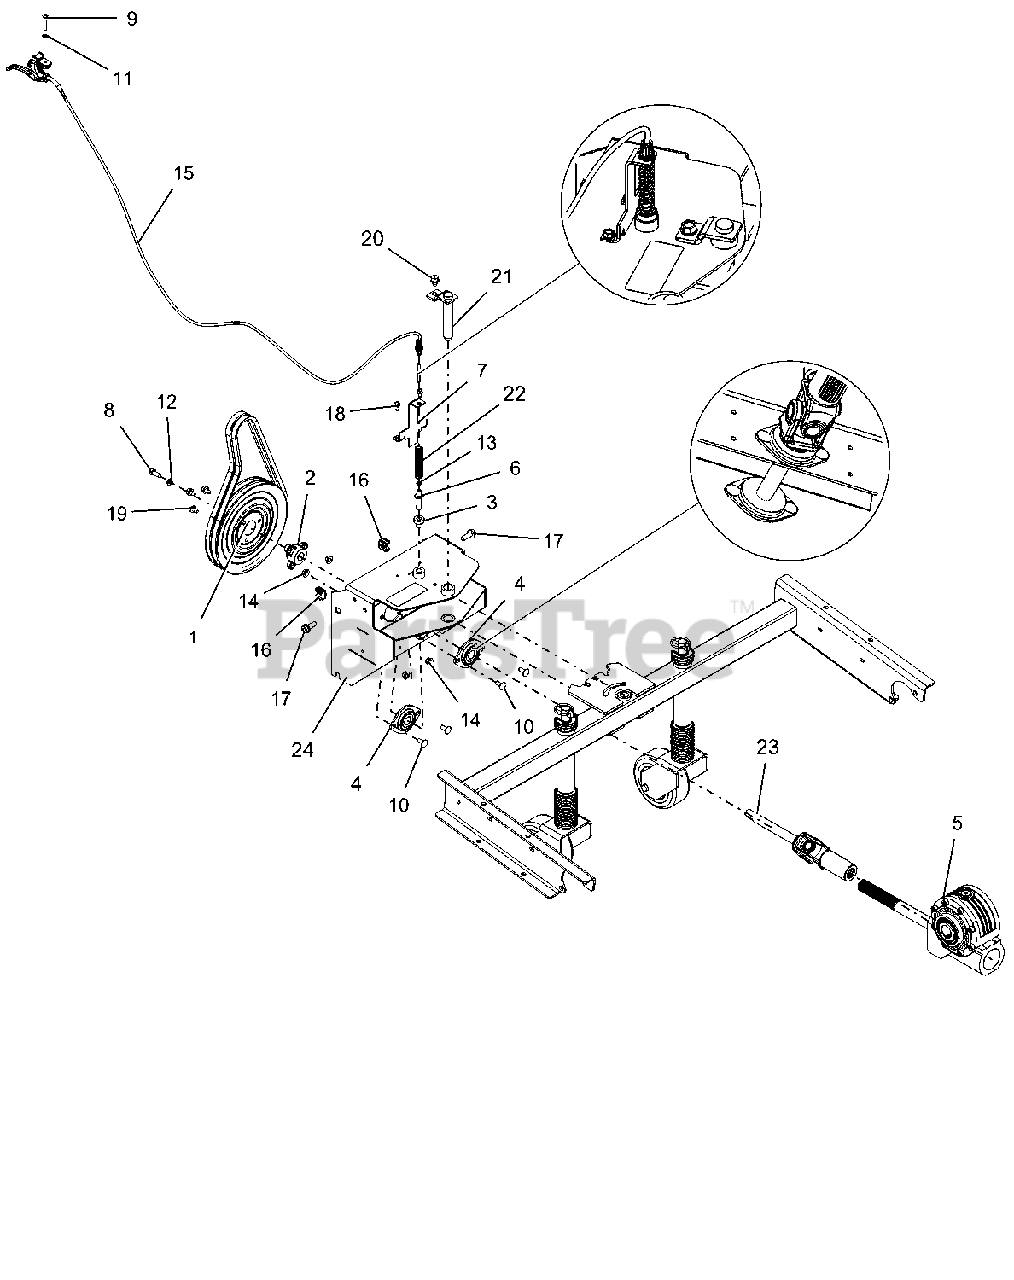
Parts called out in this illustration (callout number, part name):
1	PULLEY, SPIN FORM DUAL GROOVE
2	PULLEY HUB, BOLT-ON D-BORE .75
3	SPACER -FLANGED .390X.500X.781
4	BEARING, 2 BOLT FLANGE -.75 ID
5	GEARBOX, WORM - 8.25:1
6	PIN, ADJUSTABLE ANGLE BRUSH
7	BRKT, PIN HOLDER
8	BLT-HEX .31-24X.75 YWZC GR5
9	SCR-MCH .25-20X1.50 OVAL HD
10	BLT-RDHDSQNK .31-18X.75 G5YZ
11	WSHR-LK-INT .250 TH TYA
12	WSHR-LK .312X.097 HVY YWZC
13	NUT-HEX 10-24 YWZC
14	NUT-LK-TOP-FLG .31-18 YWZC
15	CABLE, REMOTE BRUSH LOCK
16	NUT-RETNR .38-16 TINRMAN
17	BLT-SERHFWH .375-16X1.0 YWZC
18	SCR-TAP .25-20X.50 HWH TR YWZ
19	SCR-TAP .31-18X.50 HWH TR YWZ
20	SCR-TAP .38-16X.50 HWH TR YWZ
21	WLDMT, BRUSH PIN
22	SPRING, COMPRESSION
23	DRIVELINE, SERIES 07 (U-JOINT)
24	ADAPTER, BRUSH
